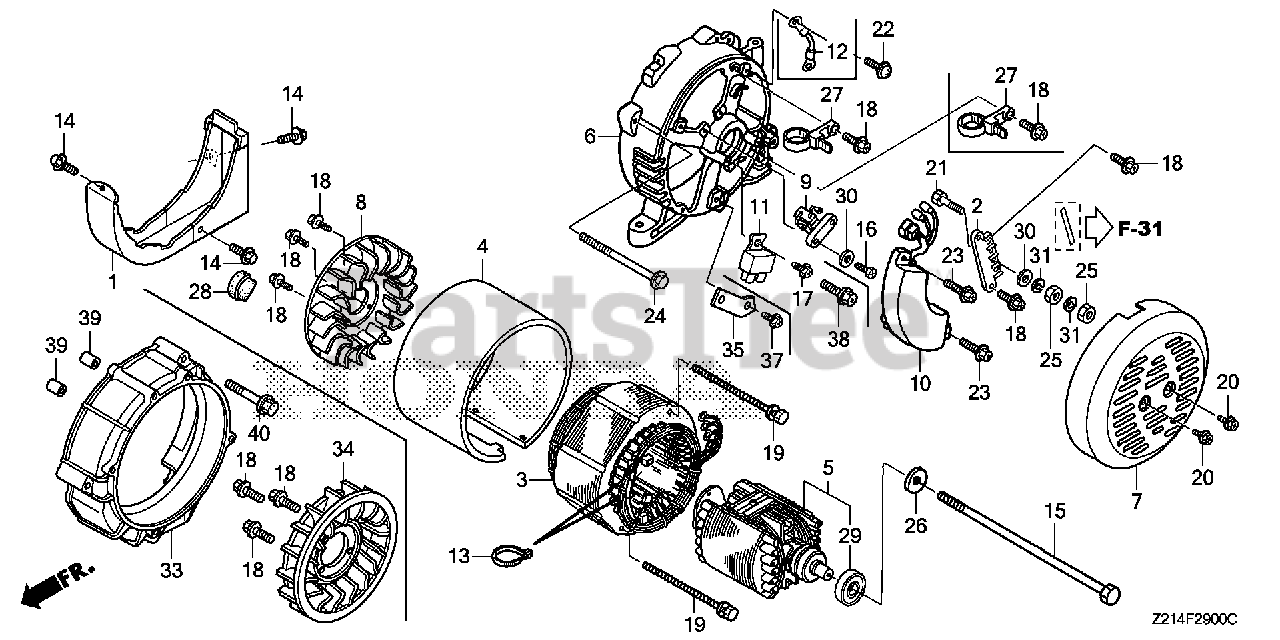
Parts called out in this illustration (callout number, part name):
2	TERMINAL, VOLT CHANGE
3	STATOR ASSY. (EM-A)
4	COVER, STATOR *NH105* (MAT BLACK)
6	HOUSING, RR.
7	COVER, GENERATOR END *NH105* (MAT BLACK)
9	BRUSH ASSY.
11	DIODE, D.C.
11	DIODE, D.C. (NOT AVAILABLE)
15	BOLT, HEX. (10X237)
17	SCREW, TAPPING (5X12)
18	SCREW, TAPPING (5X14)
20	SCREW, TAPPING (5X12)
21	BOLT, HEX. (5X20)
22	SCREW, PAN (5X12)
24	BOLT, FLANGE (6X147)
25	NUT, HEX. (5MM)
26	WASHER (10.5MM)
27	TIE, CABLE
29	BEARING ASSY. (6204)
30	WASHER, PLAIN (5MM)
31	WASHER, SPRING (5MM)
33	HOUSING, FR.
34	FAN, GENERATOR COOLING
35	BRACKET, RR. HOUSING
37	SCREW, TAPPING (5X12)
38	SCREW, TAPPING (5X18)
39	PIN, DOWEL (8X12)
40	BOLT, FLANGE (8X60)
